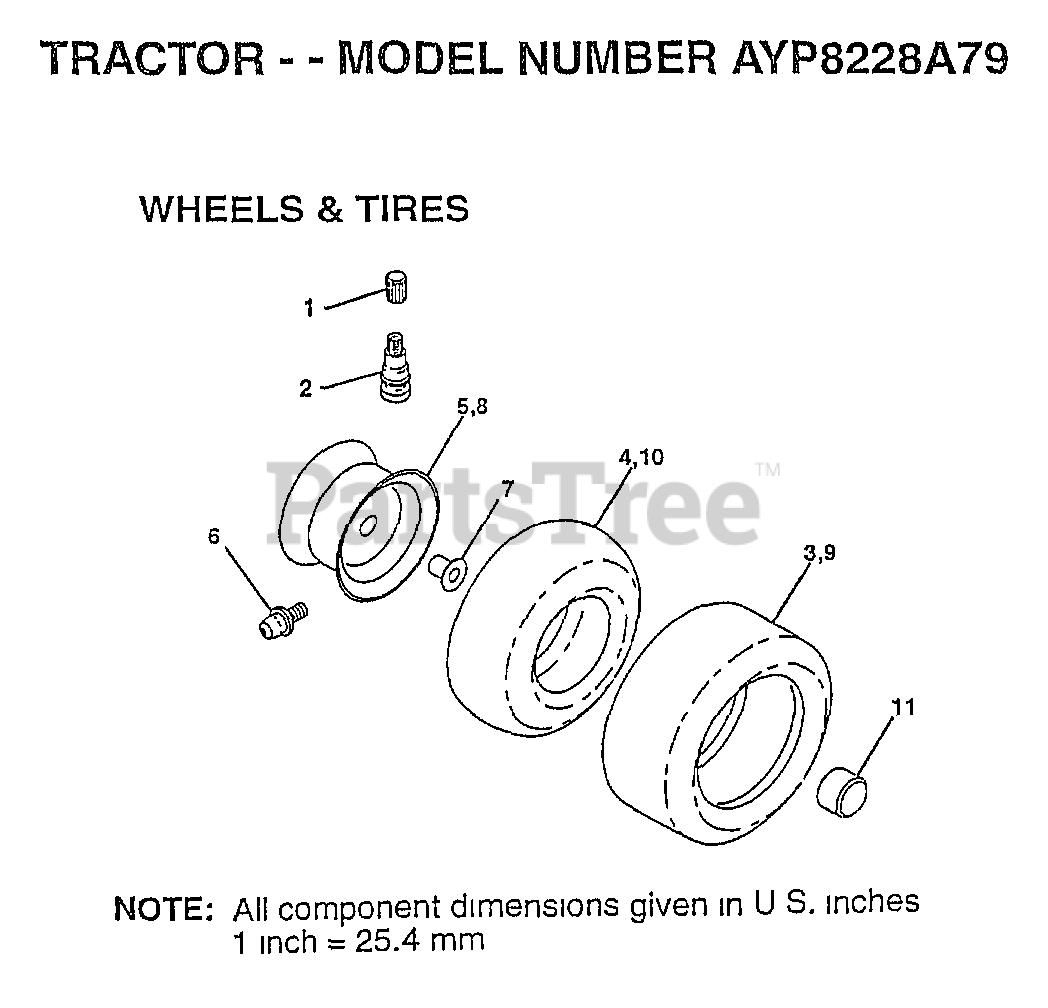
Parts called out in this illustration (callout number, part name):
1	VALVE CAP
2	VALVE STEM LT
4	TUBE.16X6.5/7.5-8
5	"RIM ASM 8"" FRT"
6	FITTING LT
7	"FLANGE, BEARING"
8	"RIM ASM 12"" REAR"
10	TUBE.23X8/10-12
11	HUB CAP
